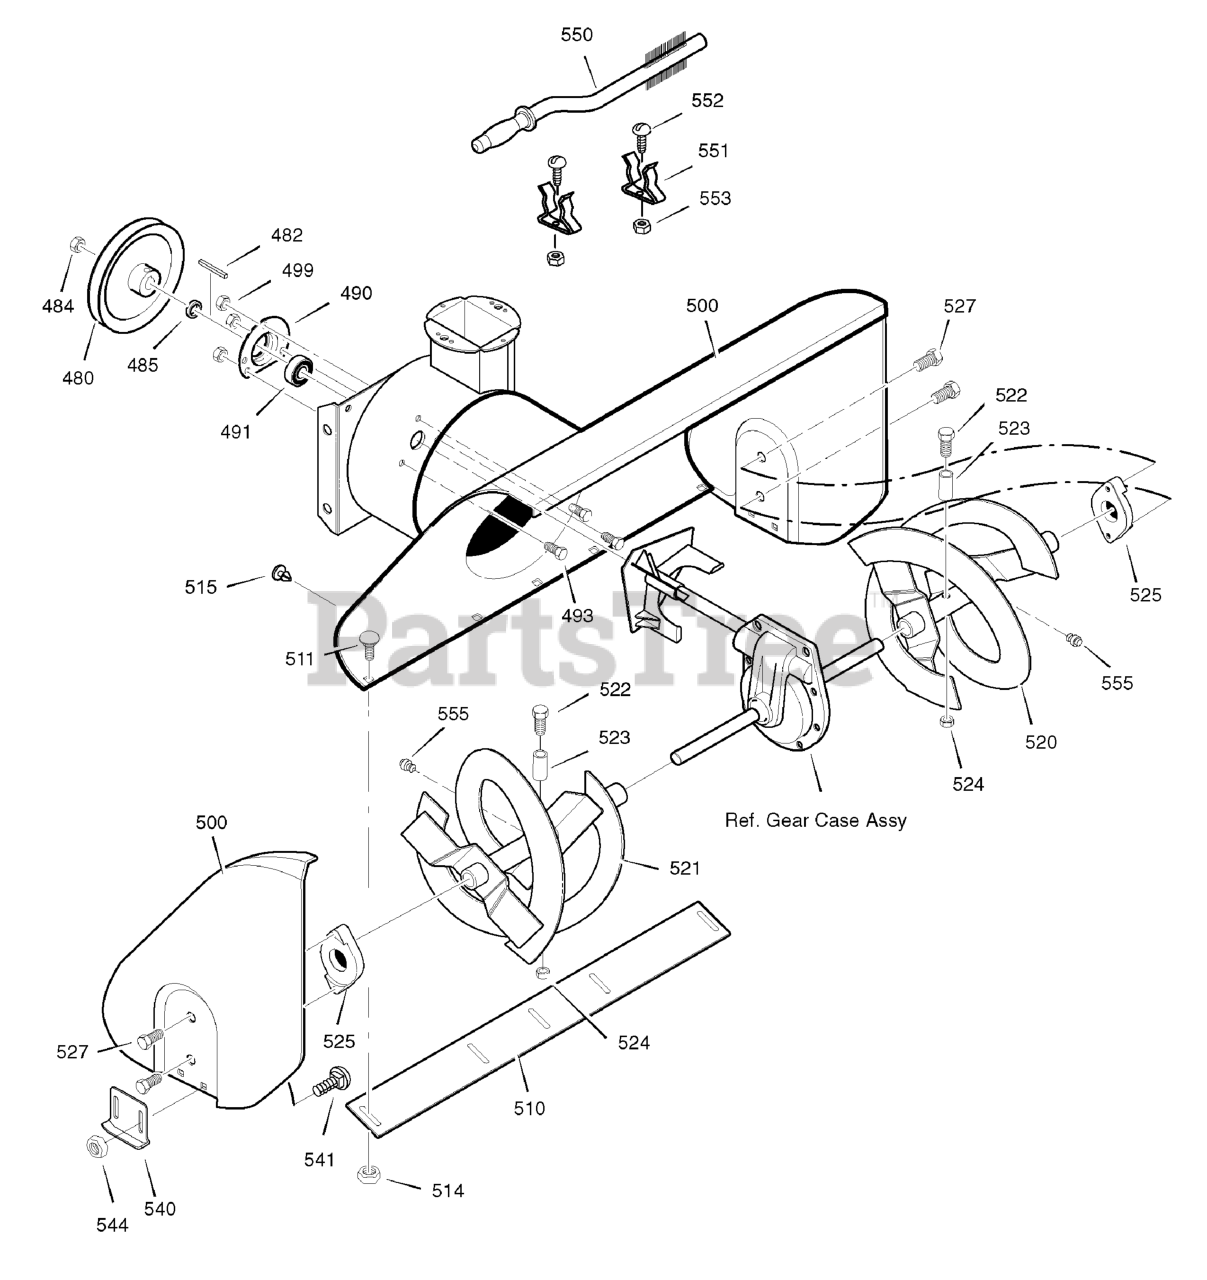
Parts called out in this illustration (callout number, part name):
480	PULLEY, 4L 8.40 OD.
482	KEY, SQUARE 3/16 X 3/4
484	NUT, .50-20 HEXWDFLLK
485	SPACER, FRICTION PULLEY
490	RETAINER, BALL BEARING
491	BEARING, BALL
493	BOLT, HEX 5/16-18 X .62
499	NUT, 5/16-18 HEXWDFLLK
500	HOUSING, ASSEMBLY
510	BLADE, SCRAPER
511	BOLT, 1/4-18 X .5
514	NUT, 5/16- 18
515	PLUG, PANEL
520	AUGER, ASSEMBLY, LH
521	AUGER, ASSEMBLY, RH
522	SCREW, 1/4-20 X 1.75
523	SPACER, SLEEVE
524	NUT, 1/4-20
525	BEARING, FLANGE
527	SCREW, 5/16-18 x 0.75
540	SKID, HEIGHT ADJUST
541	BOLT, 5/16-18 X .50
544	NUT, 5/16- 18
550	BRUSH, CLEANOUT
551	CLIP, RETAINER
552	SCREW
553	NUT
554	GREASE FITTING
